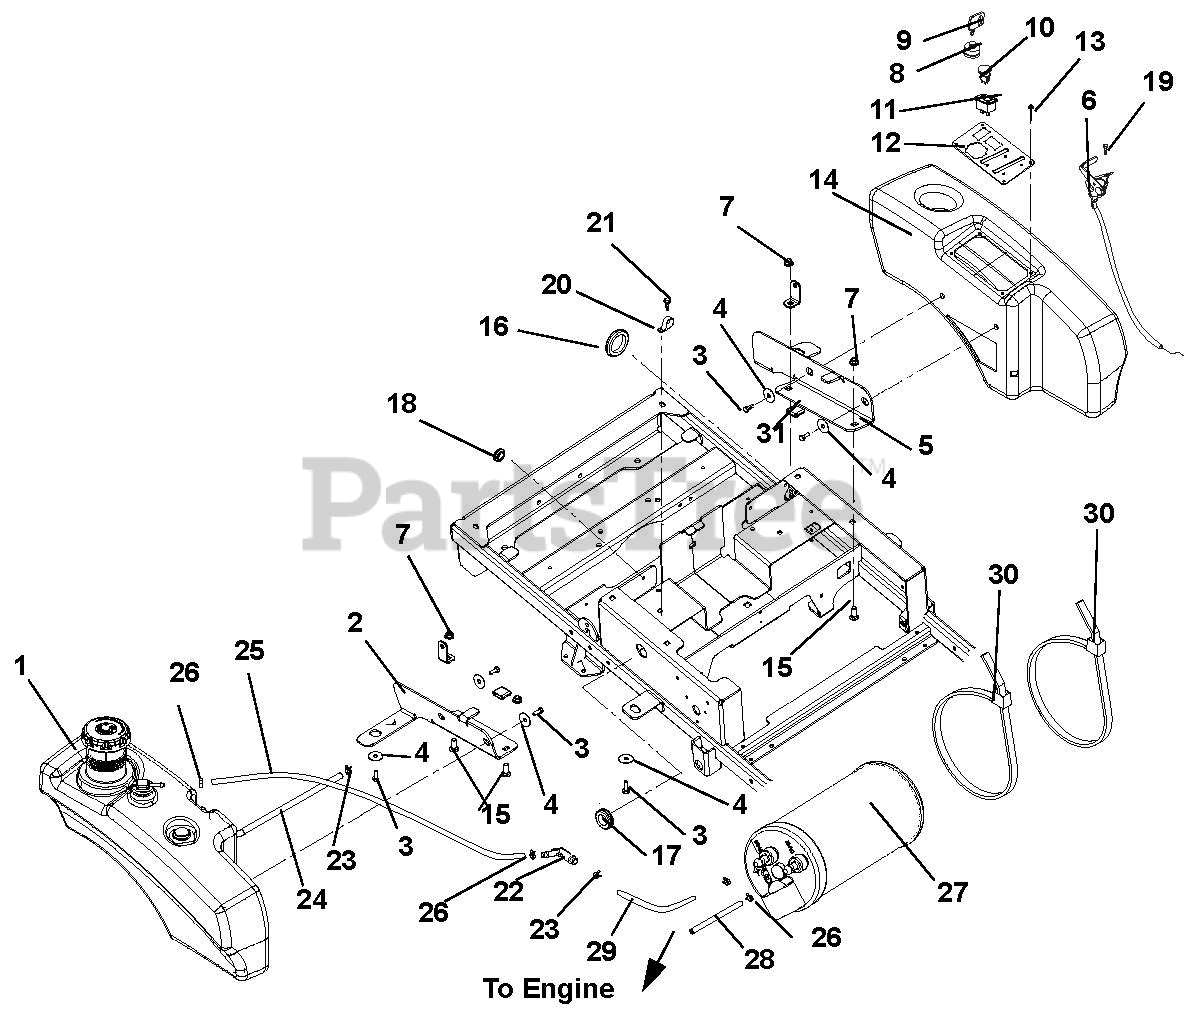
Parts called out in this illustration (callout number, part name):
1	Tank, XL Non-Permeable Fuel
2	Weldment, RH Tank Mount
3	Bolt, Serrated Hex Flange Washer Head .312-18 x .50
4	Washer, Flat Steel .347 x 1.254 x .048
5	Weldment, LH Fender Mount
6	Cable, Throttle
7	Nut, .38-16 Nyloc Flange
8	Key Switch
9	Key, w/Cap
10	Switch, Clutch
11	Hour Meter, Digital
12	Panel, Control
13	Screw, Hex .25 x 14-.75
14	Fender, XL
15	Bolt, Round Head Square Neck .38-16 x 1.00 Grade 5
16	Grommet, 2.00"
17	Grommet .125 x 1.000 ID
18	Grommet, Rubber 5/8 ID/1.13 OD
19	Screw, Tapping 10-24 x .50 Hex Washer Head Thread
20	Clamp, Cushioned Steel
21	Screw, Tap Hex Washer Head .38-16 x .5
22	Fitting, 3/16 x 1/4 90 Degree VAC
23	Clamp, Fuel Line
24	Hose, .25 Low-Perm Bulk Gas
25	Hose, .188 Low-Perm Bulk Gas
26	Clamp, Hose, Spring .188
27	400 CC Carbon Canister 3/16 PT
28	Hose, .25 Low-Perm Bulk Gas
29	Hose, .188 Low-Perm Bulk Gas
30	Tie Wrap
31	Grip, Rubber
